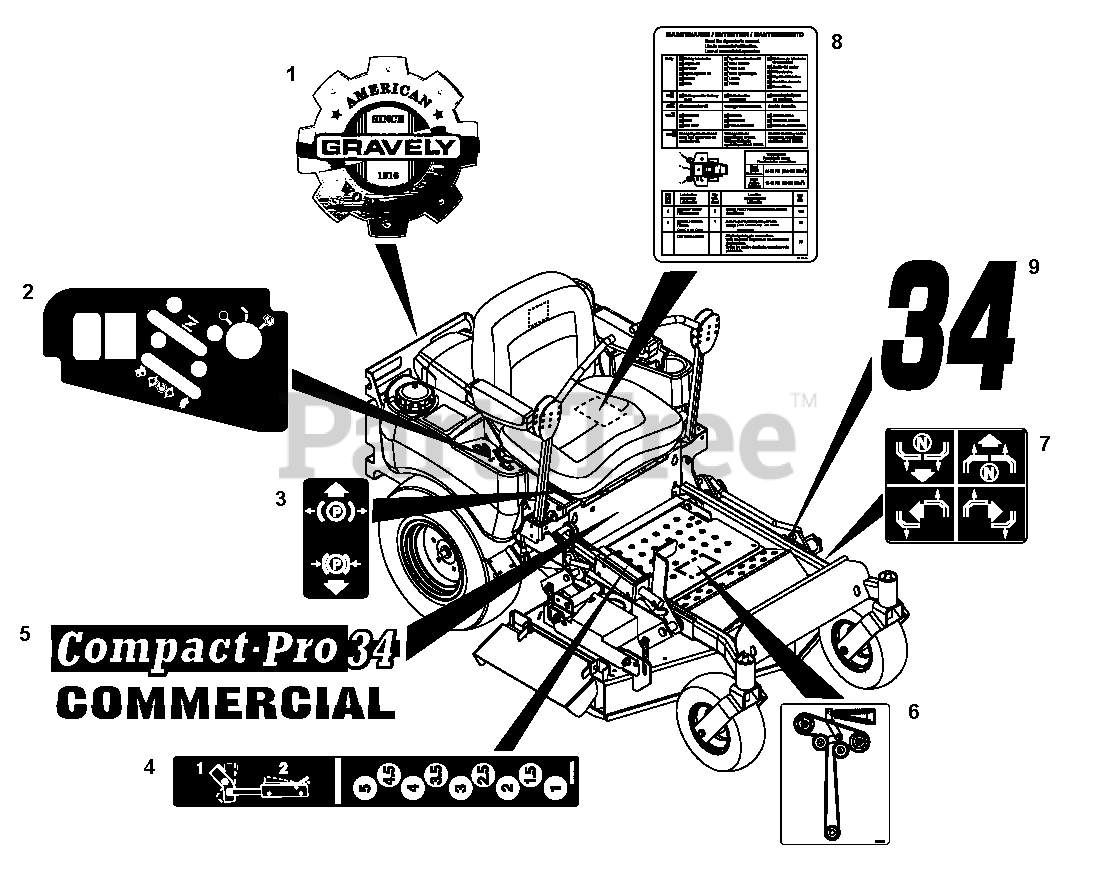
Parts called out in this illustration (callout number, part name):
1	Decal, Heritage Large
2	Decal, Control Panel
3	Decal, Parking Brake Lever
4	Decal, Height of Cut
5	Decal, Compact-Pro 34
6	Decal, Belt Diagram
7	Decal, Instructional Steering
8	Decal, Maintenance Instructions
9	Decal, 34"
